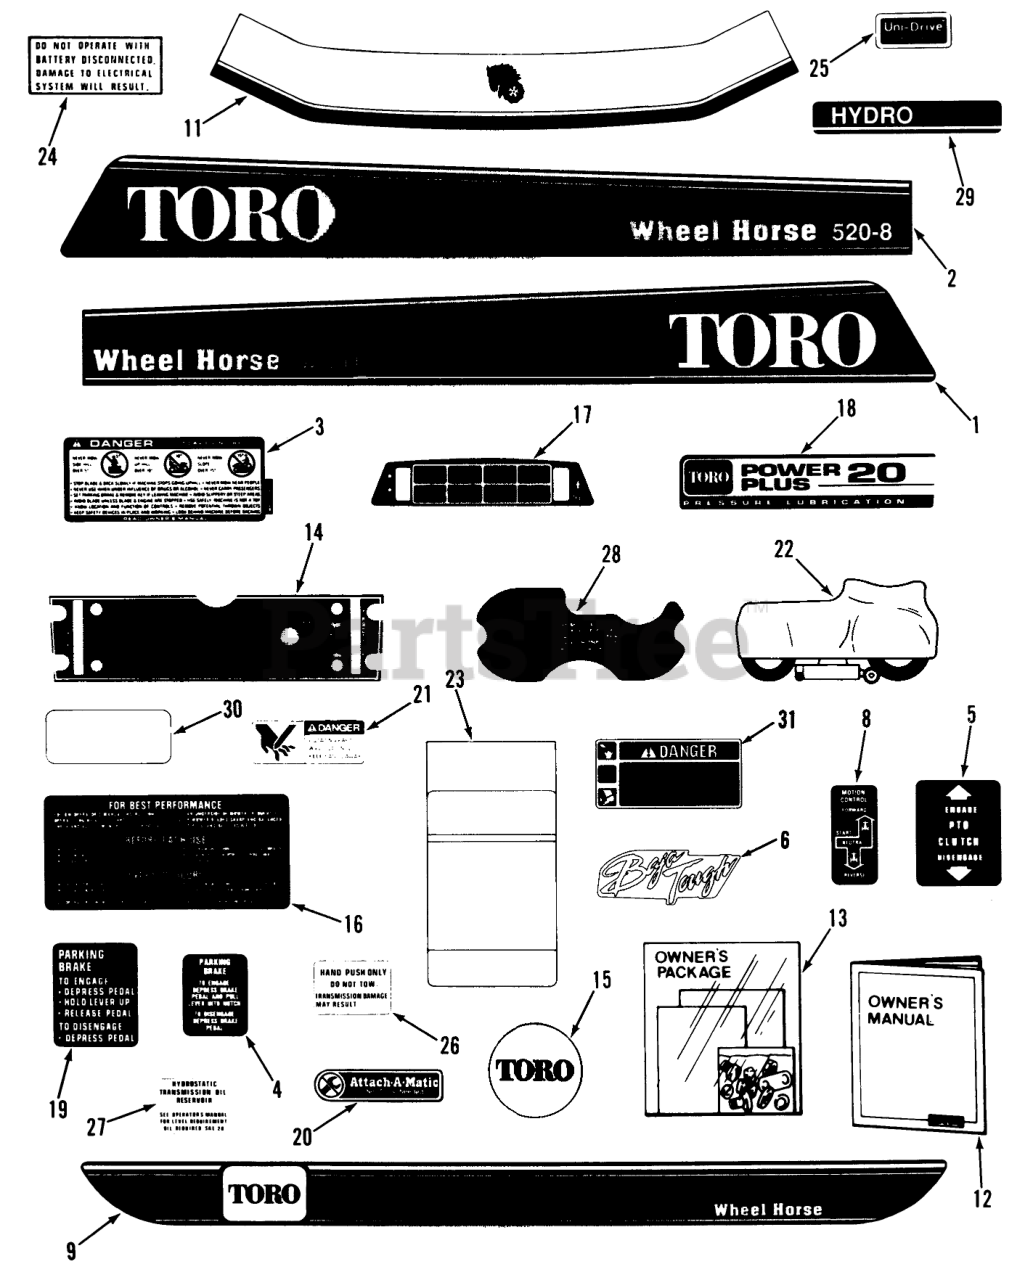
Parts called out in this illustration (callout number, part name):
1	DECAL-HOOD 520-H R H
2	DECAL-HOOD 520-H L H
3	DECAL-DANGER
4	DECAL-PARKING, BRAKE
5	DECAL PTO CLUTCH
6	DECAL-"BAJA TOUGH"
8	DECAL-MOTION CONTROL
9	DECAL-FENDER
11	DECAL-FRONT HOOD
12	Manual-Operator-s Tractor
13	Loose Parts Package
14	DECAL-FRONT PANEL
15	NAME-PLATE TORO LOGO
16	Decal-Rear Hood
17	DECAL-IND LIGHTS
18	DECAL-PWR PLUS 20 PL
19	DECAL-PARKING BRAKE
20	Decal-Attac-O-Matic
21	DECAL-DANGER
22	Plastic Cover
23	MAINTENANCE-DECAL
24	DECAL ELECT SYSTEM
25	Decal-Unidrive
26	DECAL-DO NOT TOW
27	Decal-Danger
28	DECAL-SEAT LIFTER
29	DECAL-MODEL HYDRO
30	DECAL-OVERLAY
31	DECAL-DANGER
